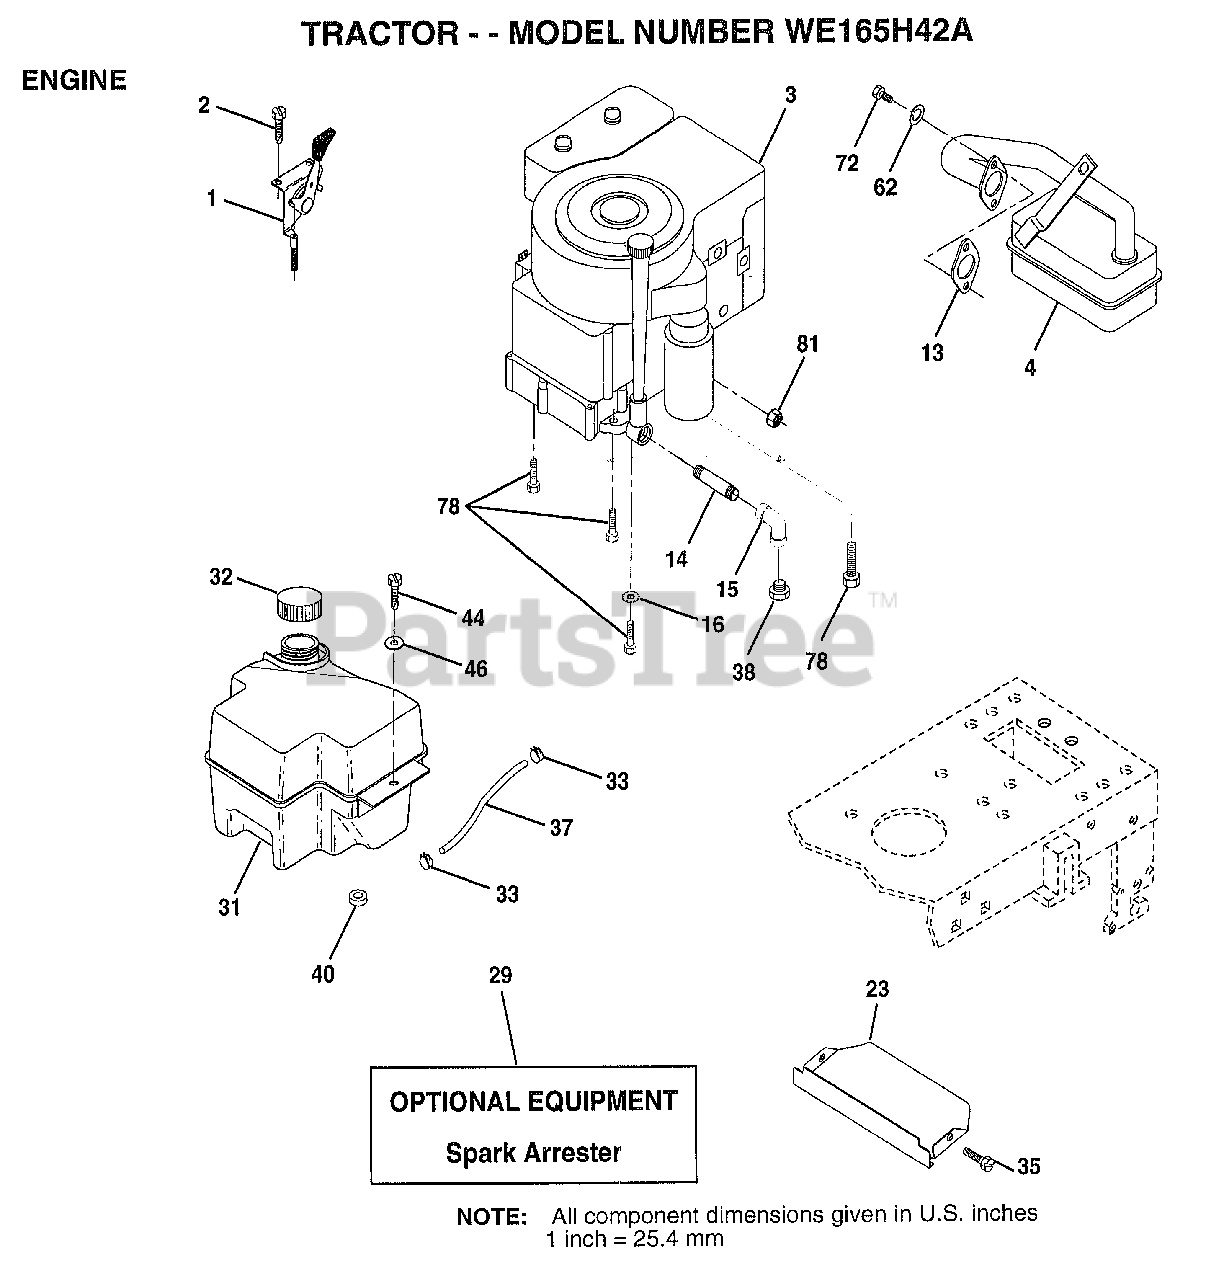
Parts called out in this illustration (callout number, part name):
1	CONTROL THROTTLE
2	SCREW LT
4	MUFFLER
13	GASKET ENG 1 313 LD TIN PLATED
14	PIPE NIPPLE
15	ELBOW
16	LOCKWASHER
23	SHIELD.BRN/DBR.GD
31	TANK.FUEL.FRONT.
32	CAP ASM FUEL
33	HOSE CLAMP
35	SCREW
37	LINE FUEL
44	SCREW HEX CRT
46	WASHER
62	LOCKWASHER
72	SCREW
78	SCREW
81	NUT
